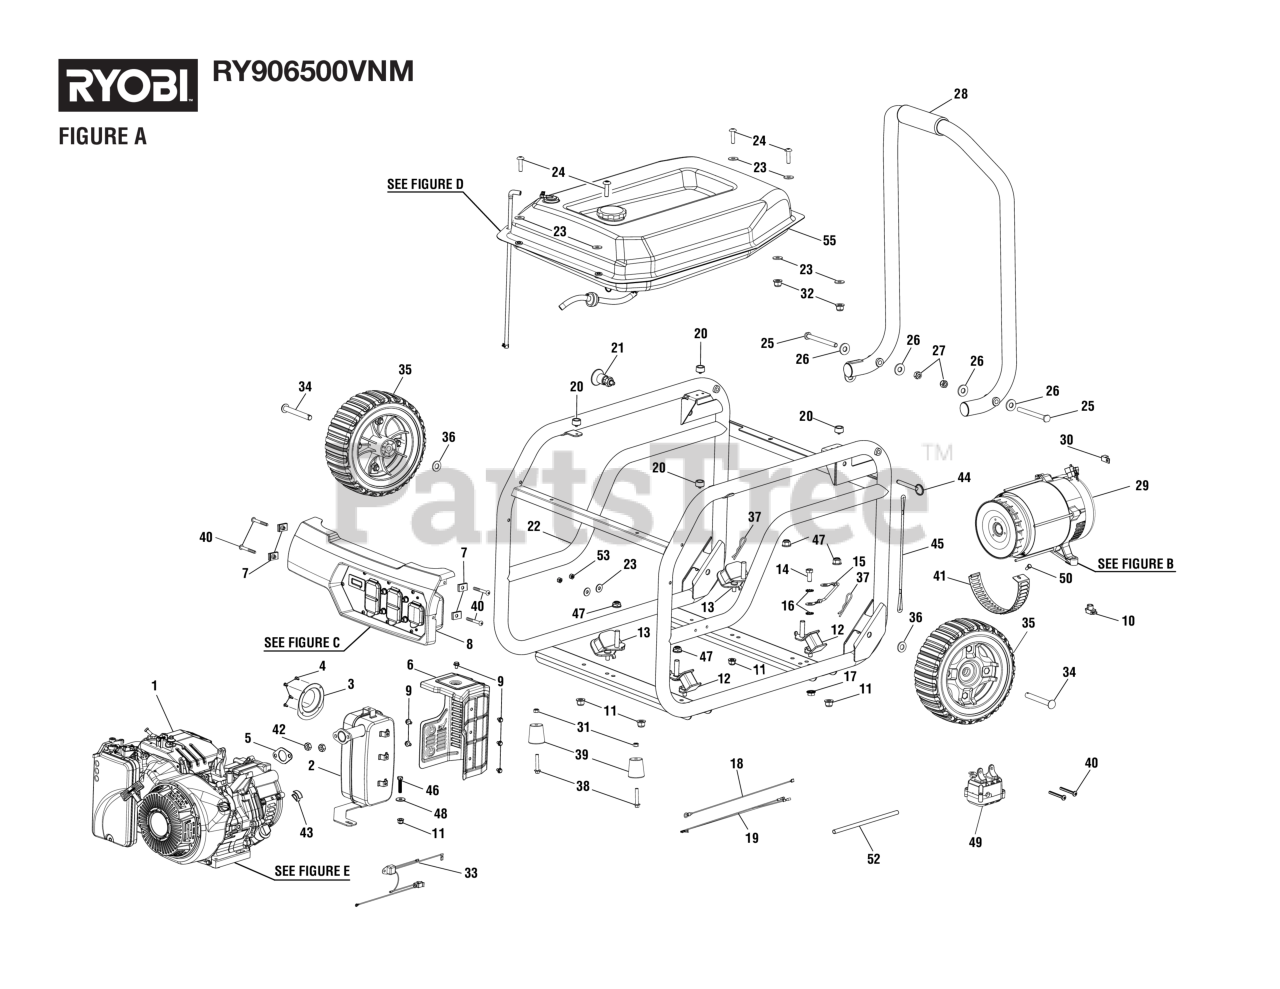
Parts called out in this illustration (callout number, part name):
3	Spark Arrester Screen
4	Screw (8-32 x 3/8 in., Pan Hd.)
5	Exhaust Gasket
6	Heat Shield
7	U-Clip (M6)
8	Control Panel Assembly
9	Bolt (M6 x 9 mm, Hex Flange Hd.)
10	Rubber Wire Protector
11	Lock Nut (M8 x 1.25 mm, Flange)
12	Engine Isolator (Large)
13	Engine Isolator (Right)
14	Bolt (5/16-18 x 3/4 in., Hex. Hd.)
15	Assembly, ground wire
16	Washer (5/16 in., External Star)
17	Flange Nut (5/16-18, Hex Hd.)
18	Off Switch Wire Assembly (Black)
19	Wire Assembly Wire (Green)
20	Handle Bumper
21	Quick Release Pin Assembly
22	Carrier Assembly
23	Washer (1/4 in., Type A)
24	Screw (1/4-20 x 1 in., T30 Torx Hd.)
25	Handle Pivot Pin (5/6-18 x 90 mm)
26	Washer ( 5/16 in.)
27	Lock Nut (5/16-18, Hex Hd.)
28	Handle Assembly
29	Generator Head Assembly.
30	Ground Lug (5/16-24) (BM903600)
31	Lock Nut (M8 x 1.25)
32	HEX NUT (1/4-20) (BC30)
33	Low Oil/CO Shutdown Wiring Harness
34	Washer (M10)
35	Handle Isolator
36	Washer (OD19.75 x ID10.5 x 1t)
37	Hitch Pin (M3)
38	Bolt (M8 x 1.25 in., Flange Hex Hd.)
39	Foot Assembly
40	Screw (M6 x 50 mm, T30 Torx Pan Hd. )
41	Fan Cover (Generator Head)
42	Hex Nut (M8 x 1.25, Special)
43	Plug (Generator Head)
44	Release Pin (5/16 x 2 in.)
45	Lanyard (3/16 in.)
46	Screw (M8 x 40 mm, Hex Hd.)
47	Lock Nut (5/16-18)
48	Washer (ID9 x OD25.4 x 2t)
49	CO Detector Shutdown Module
50	Screw (M5 x 10 mm, Hex Hd.)
51	Fuel System
52	Heat Shrink Tube
53	Lock Nut (M6 x 1 mm)
